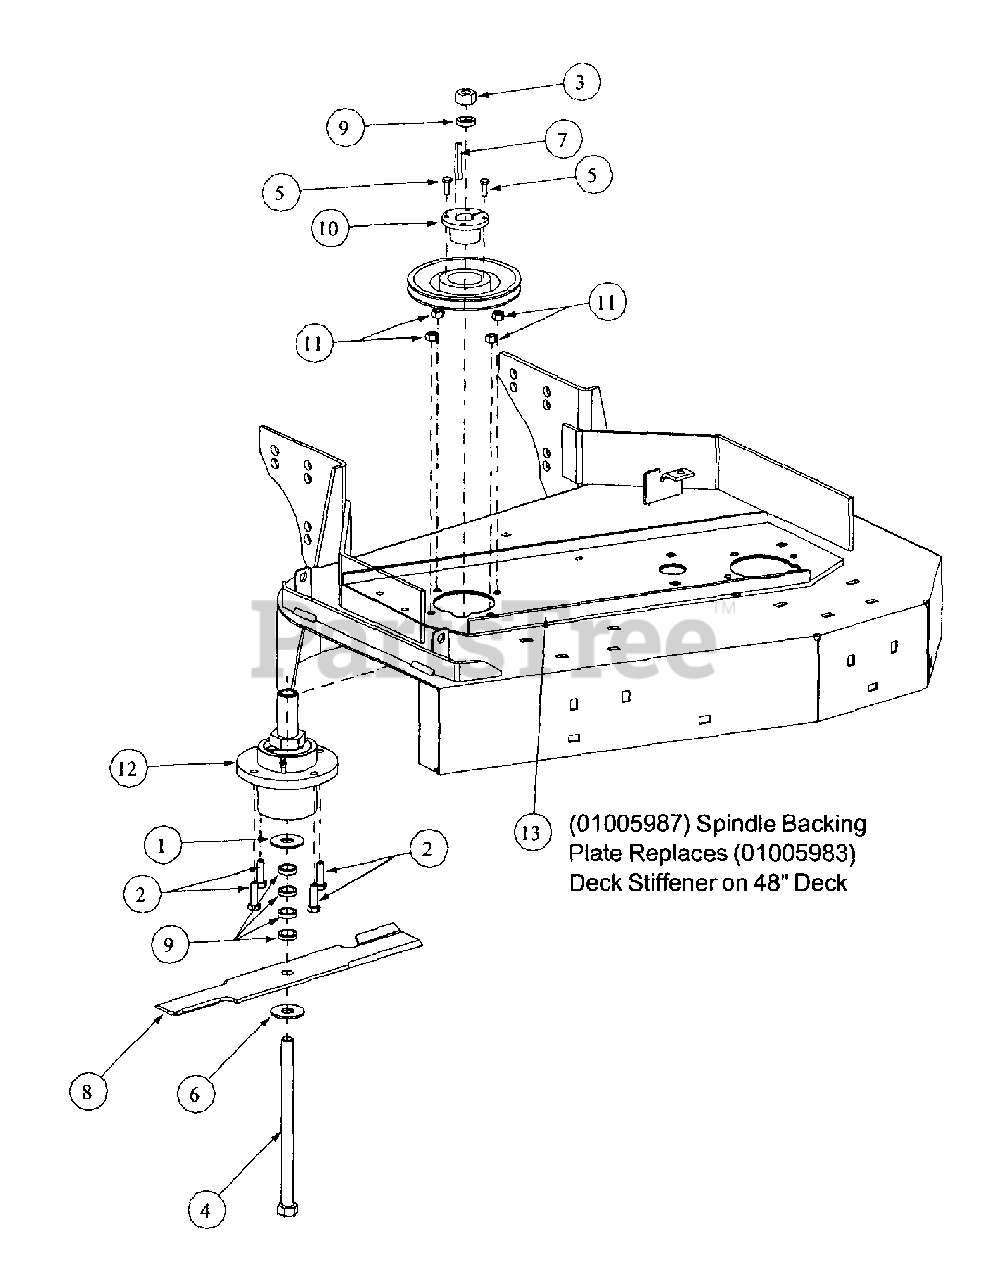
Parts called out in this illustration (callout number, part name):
1	Flat Washer, 1-1/2 x 5/8 x .05
2	Hex Cap Screw, 3/8-16 x 1-1/4
3	Hex Nut, 5/8-11
4	Hex Cap Screw, 5/8-11 x 9-1/2
5	Hex Cap Screw, 1/4-20, .75
6	Flat Washer, 5/8 Zinc
7	Key Stick, 1/4 x 1/4 x 2
8	Rotary Blade, 16-1/2
9	Blade Spacer, 5/8 ID, 1/4 Thick
10	Bushing
11	Lock Nut, 3/8-16
12	Spindle Assembly
13	Deck Plate 32" Deck
13	Deck Stiffener 48" Deck
